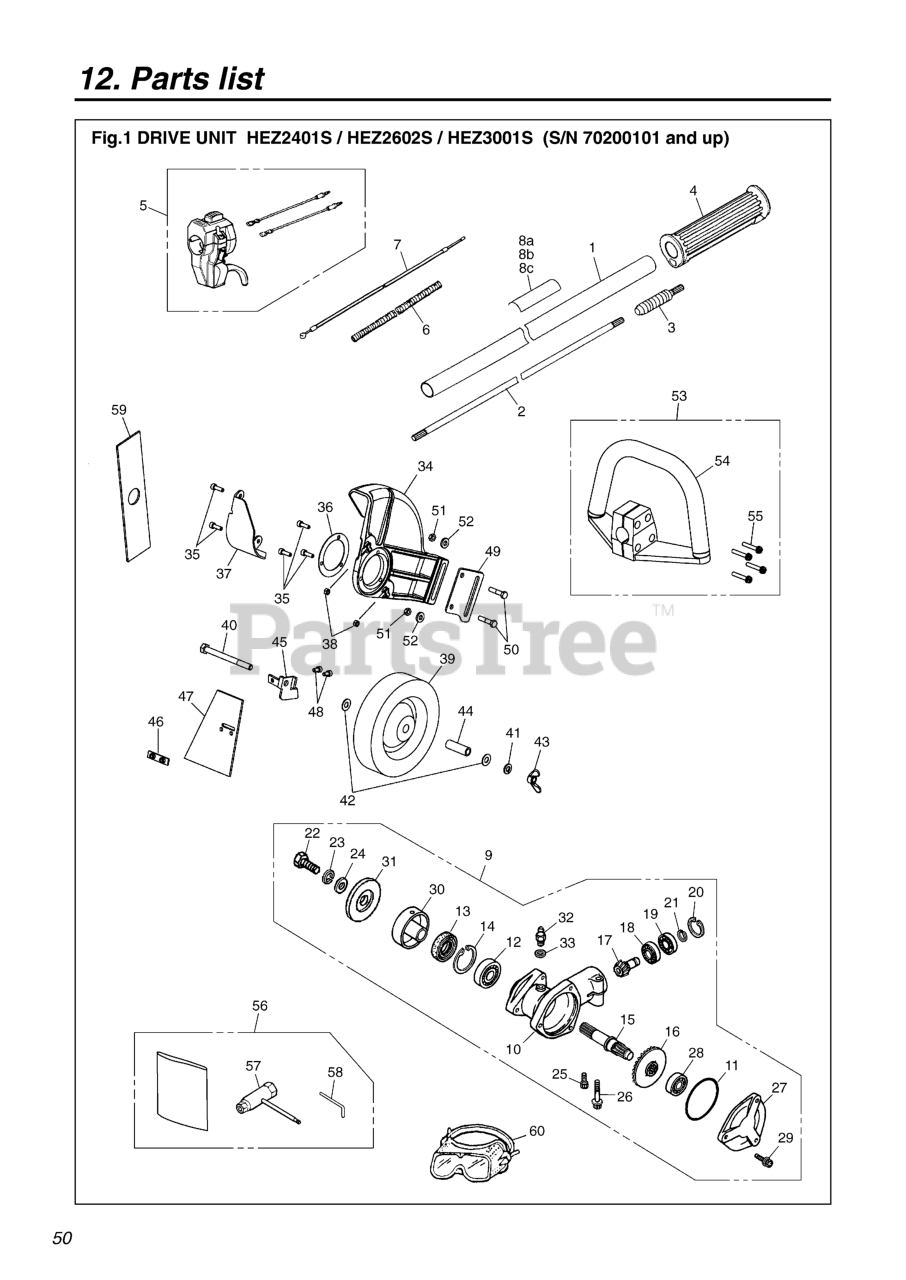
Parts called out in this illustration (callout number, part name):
1	PIPE COMP.
2	SHAFT
3	JOINT COMP.
4	GRIP
5	LEVER ASSY
6	TUBE (RPLS 4900-72141)
7	CABLE (RPLS 5580-83100)
8C	LABEL, NAME
11	O-RING
13	SEAL, OIL
14	RING, SNAP, M32 x 1.2
15	SHAFT, GEAR
16	GEAR
17	PINION
18	BEARING (RPLS T3403-13530)
19	BEARING (RPLS T3300-13531)
20	RING, SNAP, M24 x 1.2
21	RING, SNAP (RPLS T3300-13330)
22	BOLT, LH
23	WASHER (RPLS 3180-13270)
24	WASHER, M8 x 2.3 (RPLS -20823)
25	BOLT, M5 x 12
26	BOLT, M6 x 1.35
27	COVER
28	BEARING (RPLS T3403-13510)
29	BOLT
30	HOLDER (A)
31	HOLDER (B)
32	FITTING, GREASE
33	WASHER, M6 X .8
34	GUARD
35	BOLT (M5x0.8-16)
36	PLATE
37	PROTECTOR
38	NUT, M5 X 4
39	WHEEL
40	BOLT
41	WASHER, SPRING
42	WASHER, PLANE(USE 01640-20816)
44	SLEEVE
45	BRACKET
47	RUBBER (FLAP)
48	BOLT, M5 X 10
49	Main Bracket
50	BOLT
51	NUT
52	WASHER, PLANE(USE 01640-20816)
53	HANDLE ASSY. (REPLACES -14001)
54	HANDLE T
55	SCREW
56	TOOL-SET
57	SOCKET
58	BAR
59	BLADE, EDGER (RPLS 147315)
60	GOGGLE
